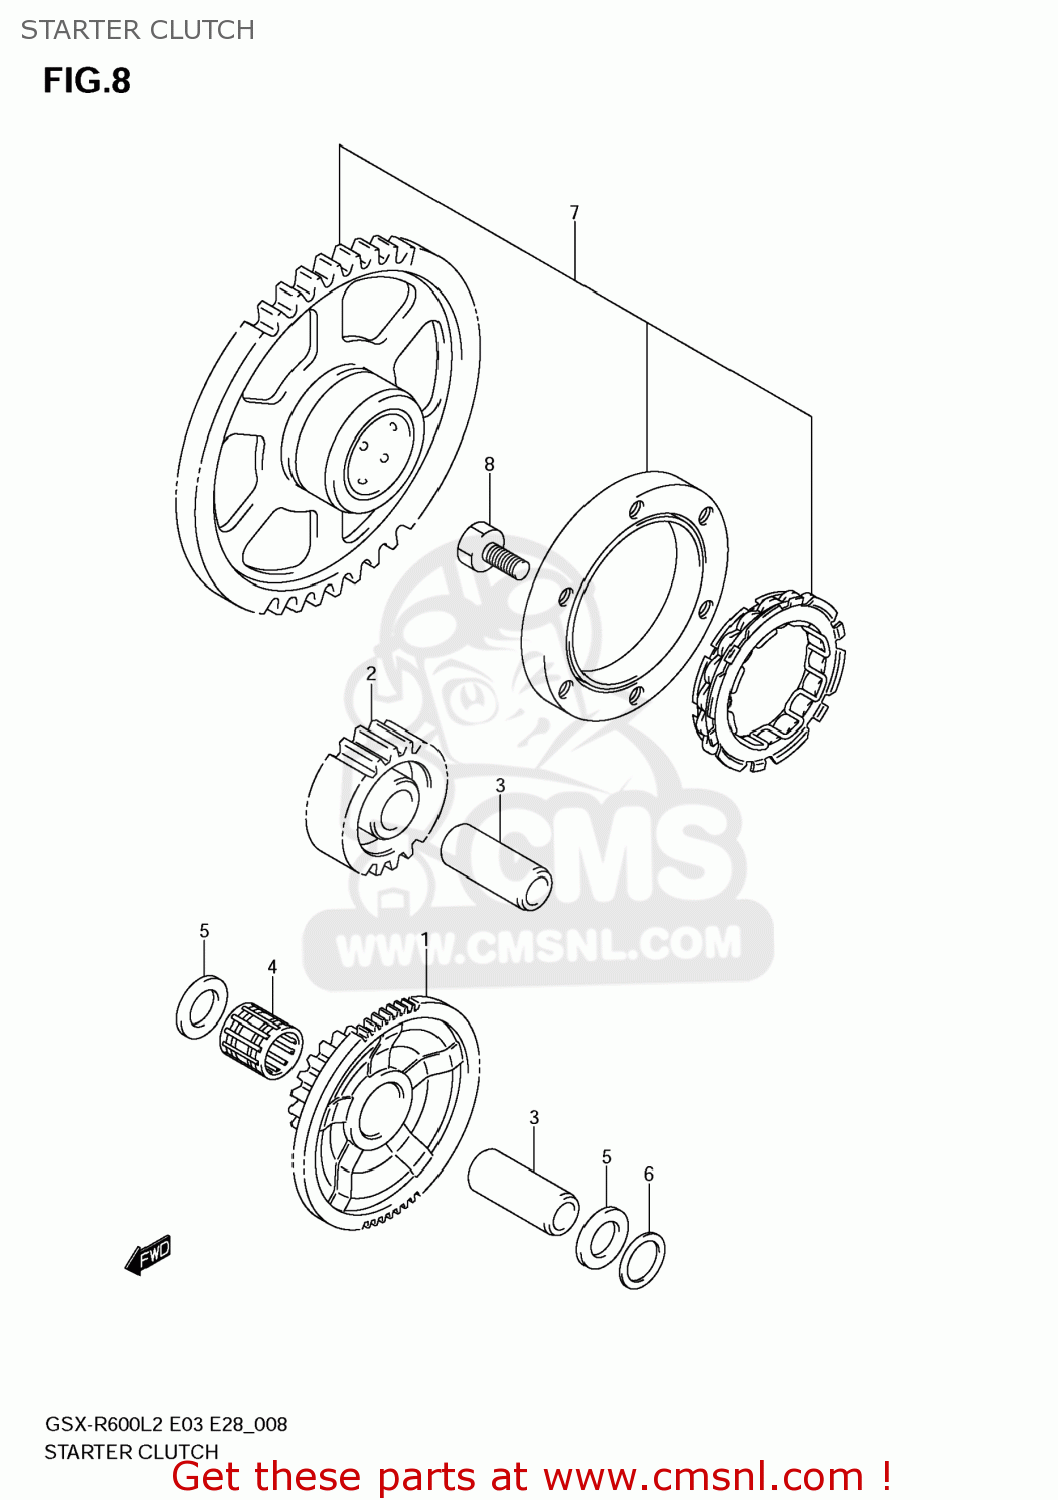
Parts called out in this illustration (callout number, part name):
1	GEAR,STARTER IDLE NO.1
2	GEAR,STARTER IDLE NO.2
3	PIN(8X12X33)
4	BEARING(12X16X16)
5	SHIM(12X20X1)
6	WASHER
7	CLUTCH SET,STARTER
8	BOLT(6X13)
